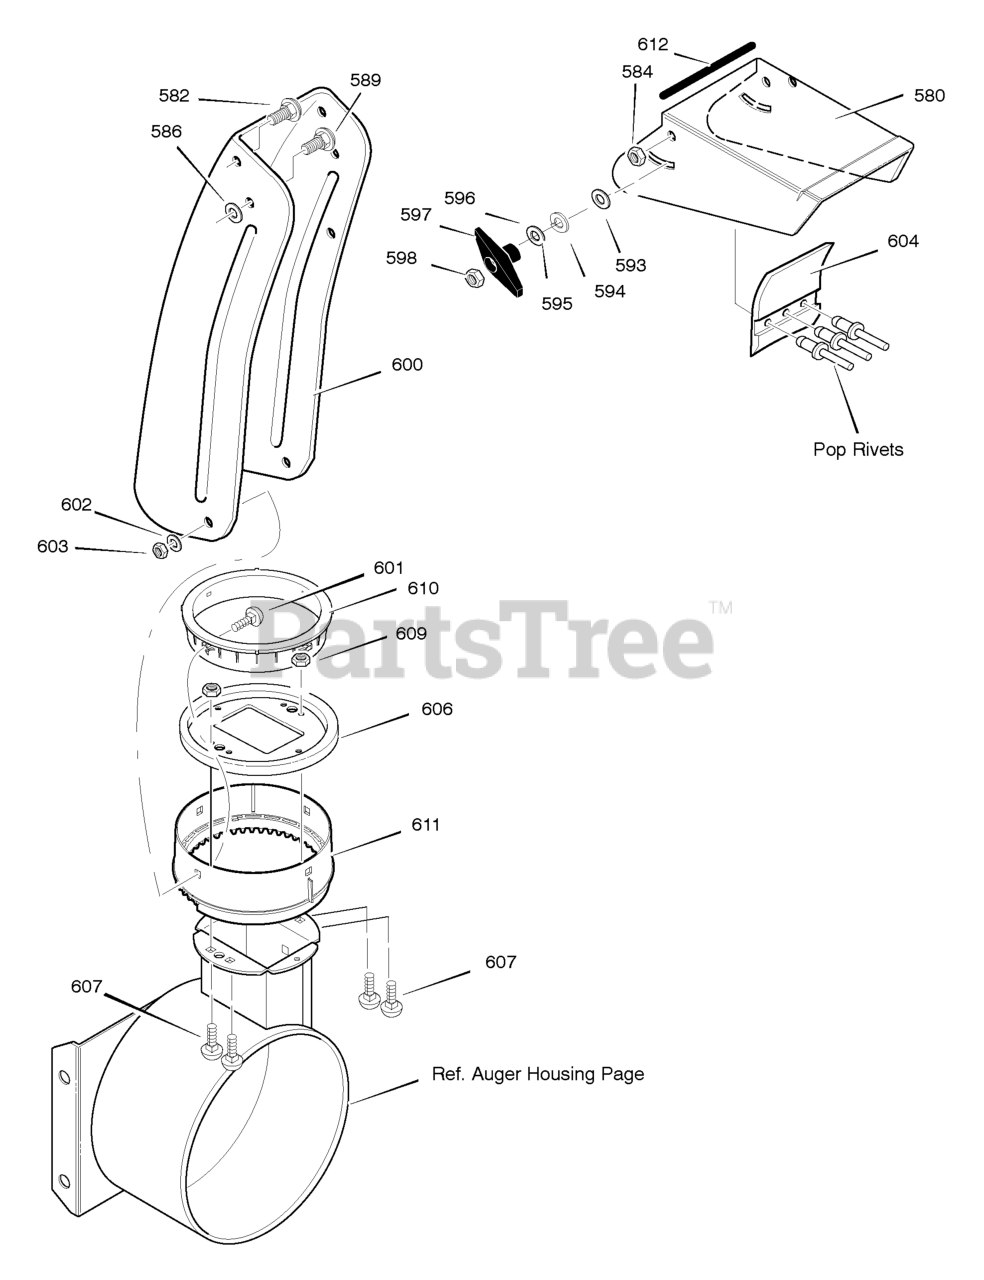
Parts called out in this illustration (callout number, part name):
58	WASHER, PLASTIC
580	CHUTE, UPPER W/REMOTE
582	SCREW, 5/16-18 x 0.75
584	NUT
593	WASHER, PLASTIC
594	WASHER, FLAT
595	WASHER, SPLIT
596	WASHER, FLAT
597	KNOB, T 3.00
598	NUT
599	SCREW, 5/16-18 x 0.75
600	CHUTE, LOWER / GUARD
602	WASHER, FLAT
603	NUT
606	CHUTE COLLAR
607	BOLT
609	NUT
610	RETAINER, RING INNER
611	RETAINER, RING OUTER
